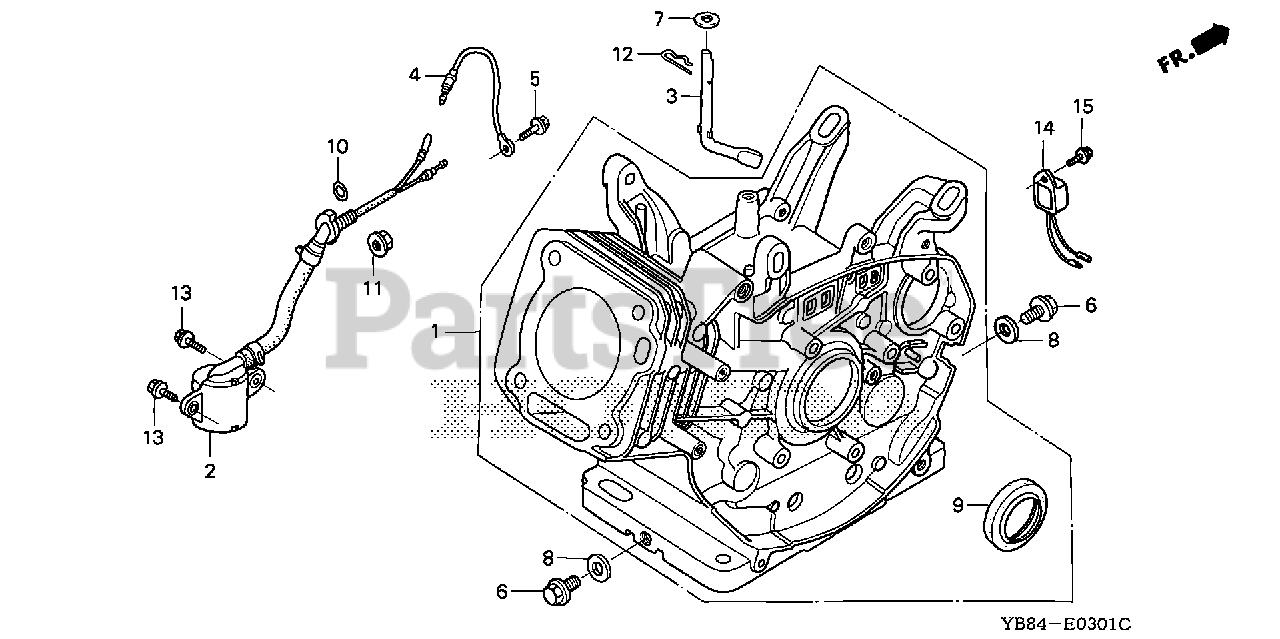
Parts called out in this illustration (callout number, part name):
1	CYLINDER ASSY.
2	SWITCH ASSY., OIL LEVEL
3	SHAFT, GOVERNOR ARM
6	BOLT, DRAIN PLUG
7	WASHER (8.2X17X0.8)
8	WASHER, DRAIN PLUG (12MM)
9	OIL SEAL (30X46X8) (NOK ASIA)
9	OIL SEAL (30X46X8)
10	O-RING (14MM) (ARAI) Use up to Engine SN 2949254.
10	O-RING (14MM) (NOK)
11	NUT, FLANGE (10MM)
12	PIN, LOCK (10MM)
13	BOLT, FLANGE (6X12) Use up to Engine SN 1543277.
